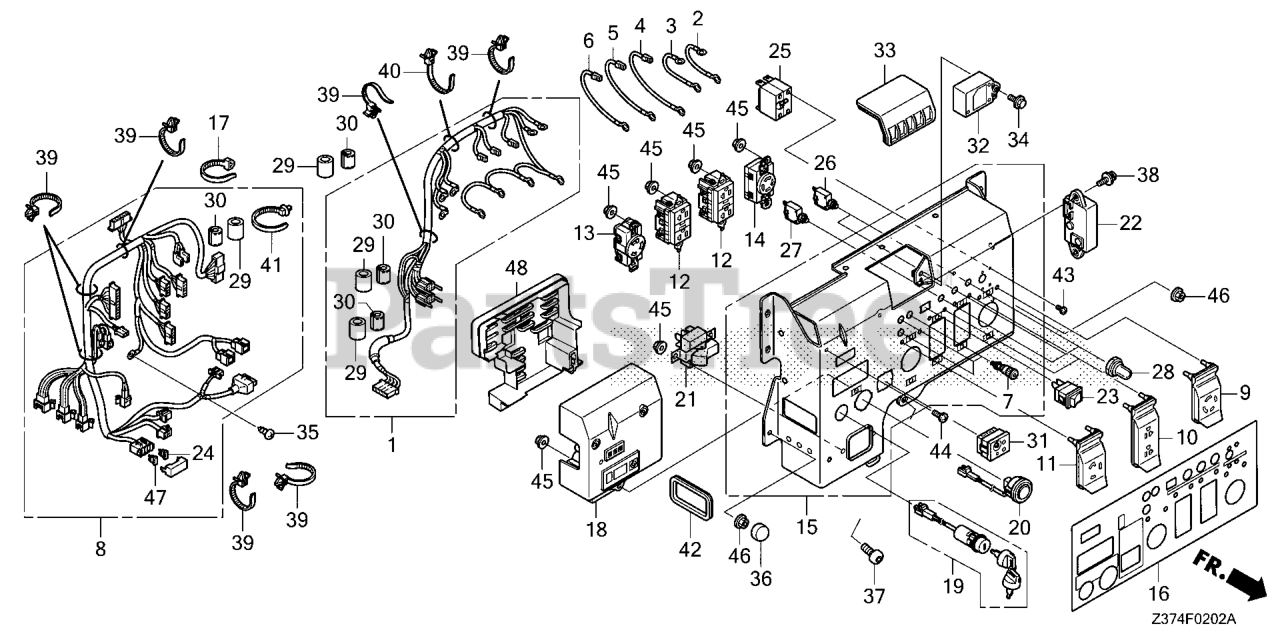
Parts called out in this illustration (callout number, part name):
1	WIRE HARNESS ASSY., MAIN
2	SUB-WIRE ASSY. (A)
3	SUB-WIRE ASSY. (B)
4	SUB-WIRE ASSY. (D)
5	SUB-WIRE ASSY. (E)
6	SUB-WIRE ASSY. (F)
7	SOCKET, COMPOSITE
8	WIRE HARNESS ASSY., CONTROL
9	COVER, RECEPTACLE (30A-125/250V)
10	COVER, RECEPTACLE (20A-125V)
11	COVER, RECEPTACLE (30A-125V)
12	RECEPTACLE (20A-125V) (GFCI)
13	RECEPTACLE (30A/125V)
13	RECEPTACLE (30A-125V)
14	RECEPTACLE (30A/125-250V)
14	RECEPTACLE (30A-125/250V)
15	PANEL, CONTROL
16	MARK, PANEL
17	BAND, TUBE (NOT AVAILABLE)
18	CONTROL UNIT, GENERATOR
19	SWITCH ASSY., COMBINATION
20	SWITCH ASSY., START
21	SWITCH ASSY., VOLT CHANGE
22	SENSING UNIT (CO)
23	SWITCH, AUTO-THROTTLE (OTAX)
24	FUSE, BLADE (3A)
25	PROTECTOR, CIRCUIT (30A)
26	PROTECTOR, CIRCUIT (20A) (WHITE)(TYCO)
26	PROTECTOR, CIRCUIT (20A) (BLACK)(JOEMEX)
27	PROTECTOR, CIRCUIT (30A) (WHITE)
27	PROTECTOR, CIRCUIT (30A) (BLACK)
28	COVER, CIRCUIT PROTECTOR
29	SUPPORTER, FILTER
30	FILTER, SUB NOISE (AC)
31	LED ASSY., INDICATER
32	UNIT KIT, BLUETOOTH (ISOLATE)
33	COVER, BLUETOOTH UNIT
34	BOLT, FLANGE (5X14)
35	SCREW, TAPPING (5X12)
36	CAP, BOLT (6MM)
37	BOLT, FLANGE TORX (6X10)
38	BOLT-WASHER (5X15) (TORX)
39	STRAP, CABLE (105MM) *NH1* (Honda Code 1685536). (BLACK)
40	BAND, WIRE HARNESS
41	CLIP, HARNESS BAND (145MM) (BLACK)
42	GROMMET, CONTROL HARNESS
43	SCREW, PAN (3X5) (NOT AVAILABLE)
44	SCREW, PAN (5X12)
45	NUT, FLANGE (4MM)
46	NUT, FLANGE (6MM)
47	FUSE, BLADE (15A)
48	COVER, GENERATOR CONTROL UNIT
